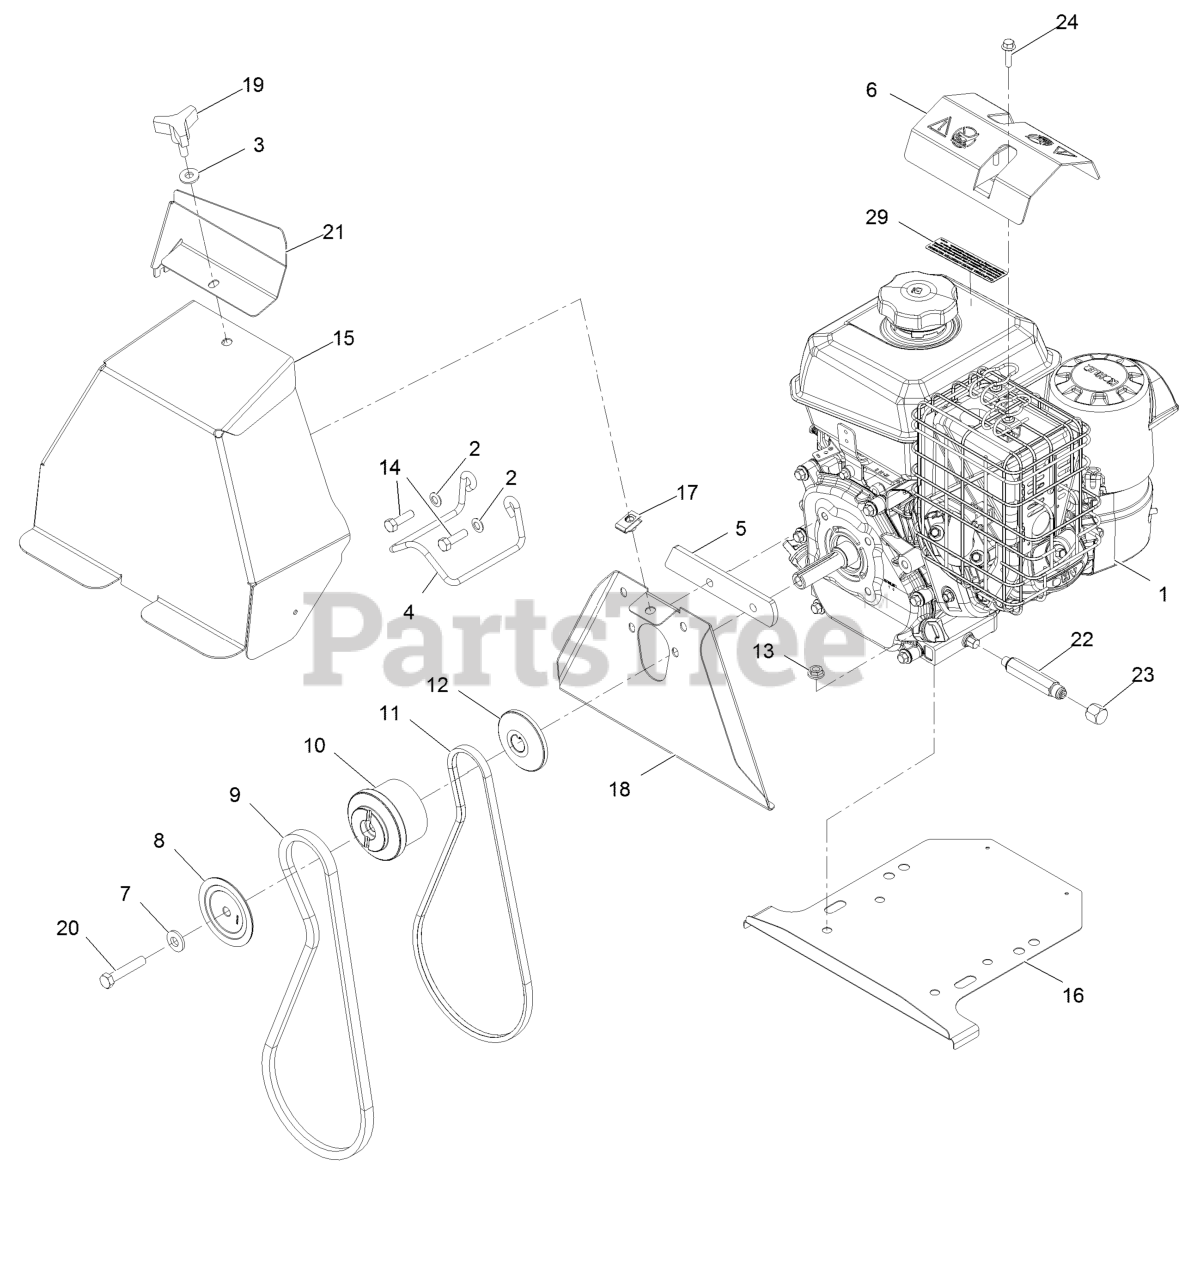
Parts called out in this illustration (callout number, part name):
2	Washer-Belleville
3	Washer-Spring Disc 5/16
4	Guide-Belt
5	Spacer-Cover, Belt
6	Deflector-Debris, Muffler
7	Washer-Spring Disc 3/8
8	Sheave-Half, Impeller
9	Belt
10	Pulley-Engine, Center
11	V Belt-Traction
12	Sheave-Half, Traction
13	Nut-Whizlock 5/16-18
14	Bolt-HH 5/16-24 X 1 1/8
15	Cover - Belt
16	Shield-Drive
18	Cover-Belt, Back
20	Screw-HH
21	Shield-Ice, Kc Ch270
22	Adapter
24	Screw-HHF
29	Decal-Arrester, Spark
